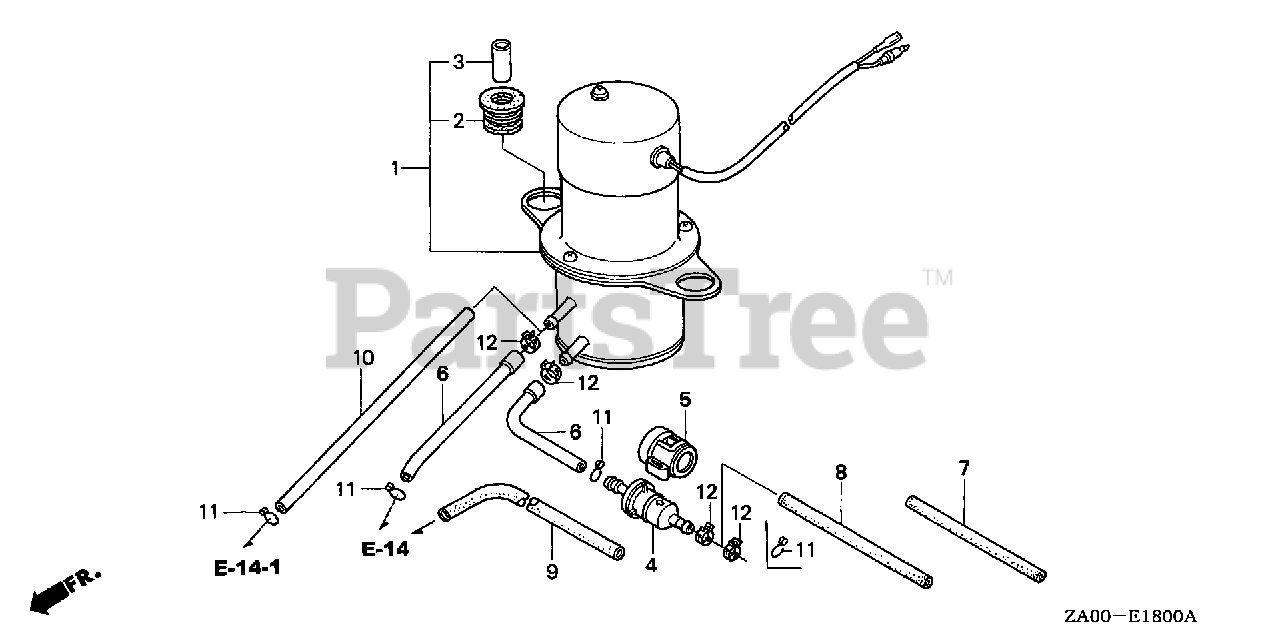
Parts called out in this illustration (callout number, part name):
4	FILTER, FUEL
9	BULK HOSE, FUEL (4.5X1000) (4.5X360)
11	CLIP, TUBE (B8)
12	CLAMP, TUBE (D8.5)
